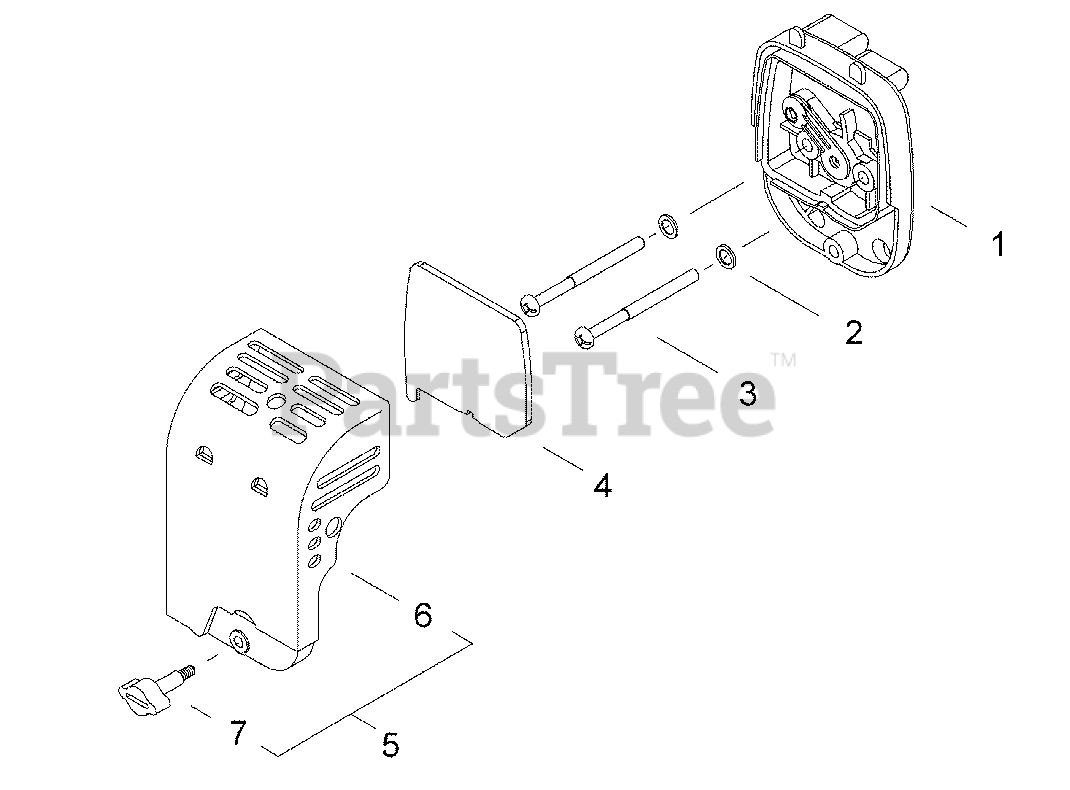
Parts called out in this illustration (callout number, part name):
1	CASE ASSY, AIR FILTER
2	WASHER 5 MM
3	SCREW M5×60
4	FILTER, AIR
5	COVER ASSY, AIR FILTER
6	COVER, AIR FILTER
7	THUMBSCREW M5
